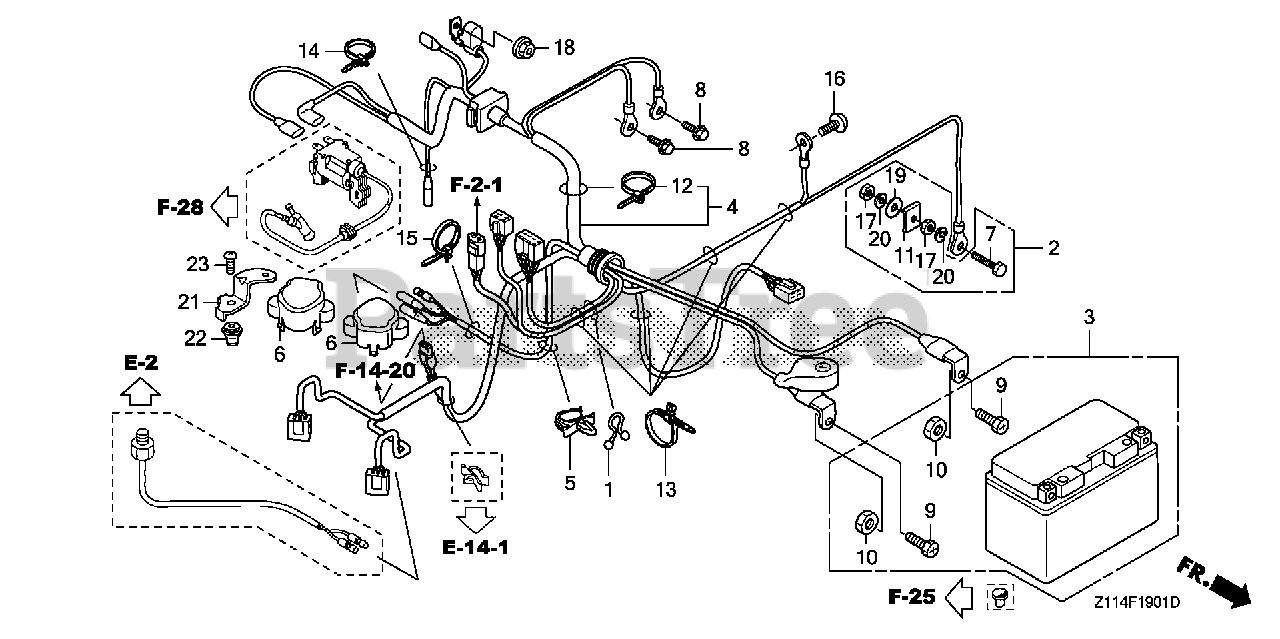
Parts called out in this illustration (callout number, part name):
1	CLIP, BREATHER TUBE PROTECTOR
1	CLIP, TUBE (26)
2	TERMINAL SET, GROUND
3	BATTERY (YTZ14S) (YUASA) (MSDS)
4	WIRE HARNESS ASSY., ENGINE
5	CLIP B, HARNESS
6	COVER, THROTTLE MOTOR
7	BOLT, HEX. (6X28)
8	BOLT, FLANGE (6X12) (CT200)
9	BOLT, BATTERY TERMINAL
10	NUT, BATTERY TERMINAL
11	RETAINER (6MM)
12	STRAP, CABLE (118MM) *NH1L* (Honda Code 1170653). (BLACK)
13	STRAP, CABLE (105MM) *NH1* (Honda Code 1685536). (BLACK)
14	BAND, CABLE
15	CLIP B, HARNESS BAND (129.4MM) (DARK BROWN)
16	SCREW, PAN (5X8)
17	NUT, HEX. (6MM)
18	NUT-WASHER (8MM)
19	WASHER, PLAIN (6MM)
20	WASHER, SPRING (6MM)
